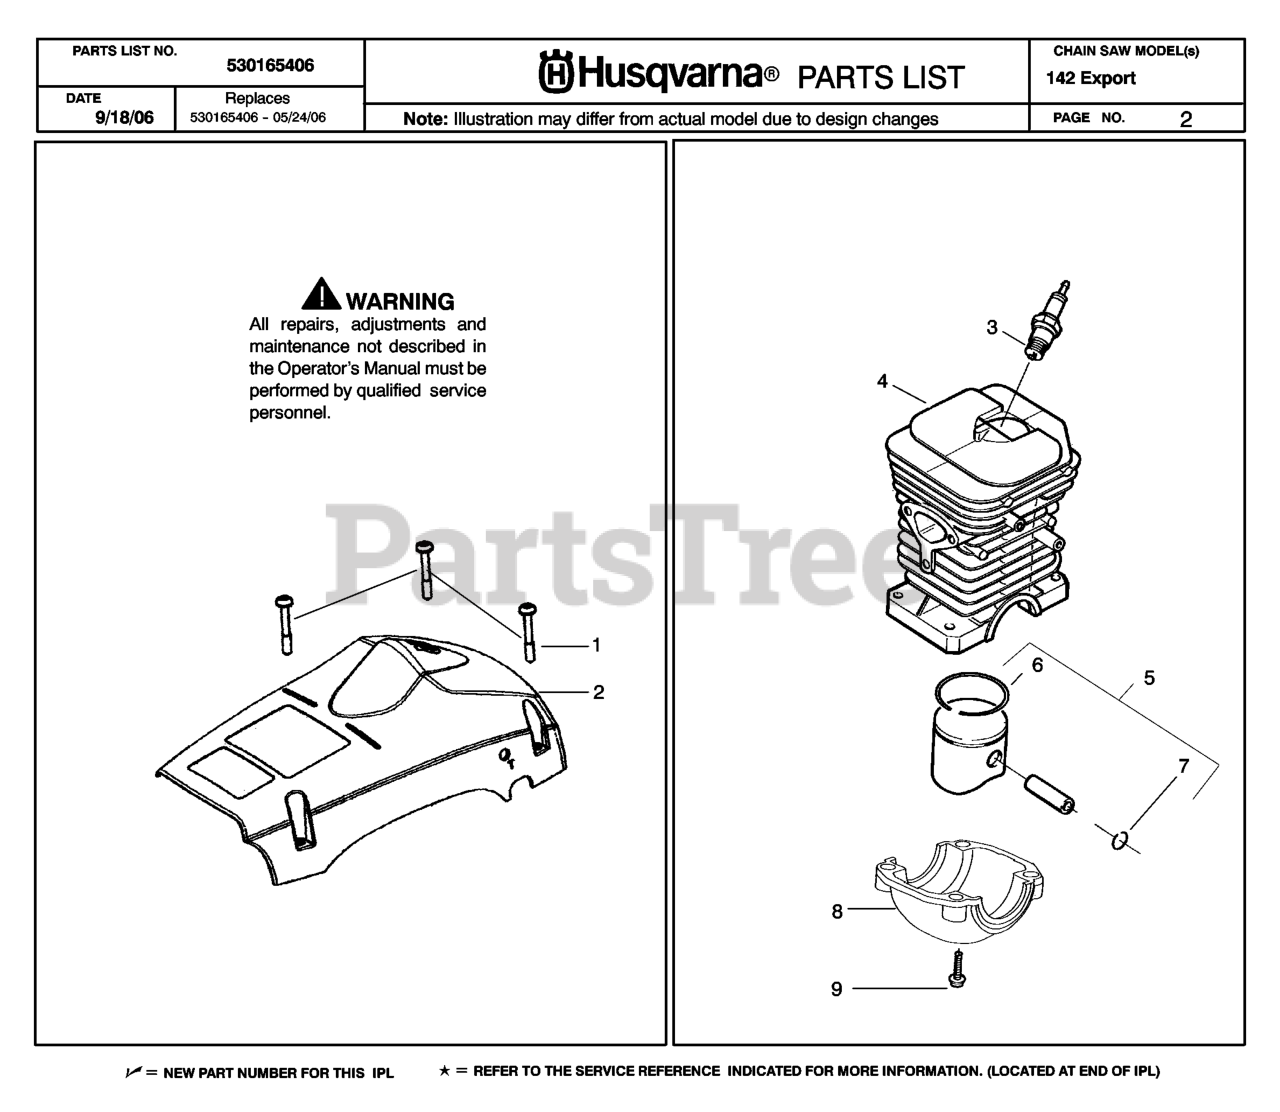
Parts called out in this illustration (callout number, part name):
2	CYLINDER SHIELD
3	Spark Plug (RCJ--7Y)
4	CYLINDER ASSY/141
5	KIT-PISTON
6	PISTON RING HV41
7	C-CLIP,PSTN PIN 36/41
8	CAP-CRANKSHAFT
9	SCREW-M5-0.8 X 25MM(TAP)
